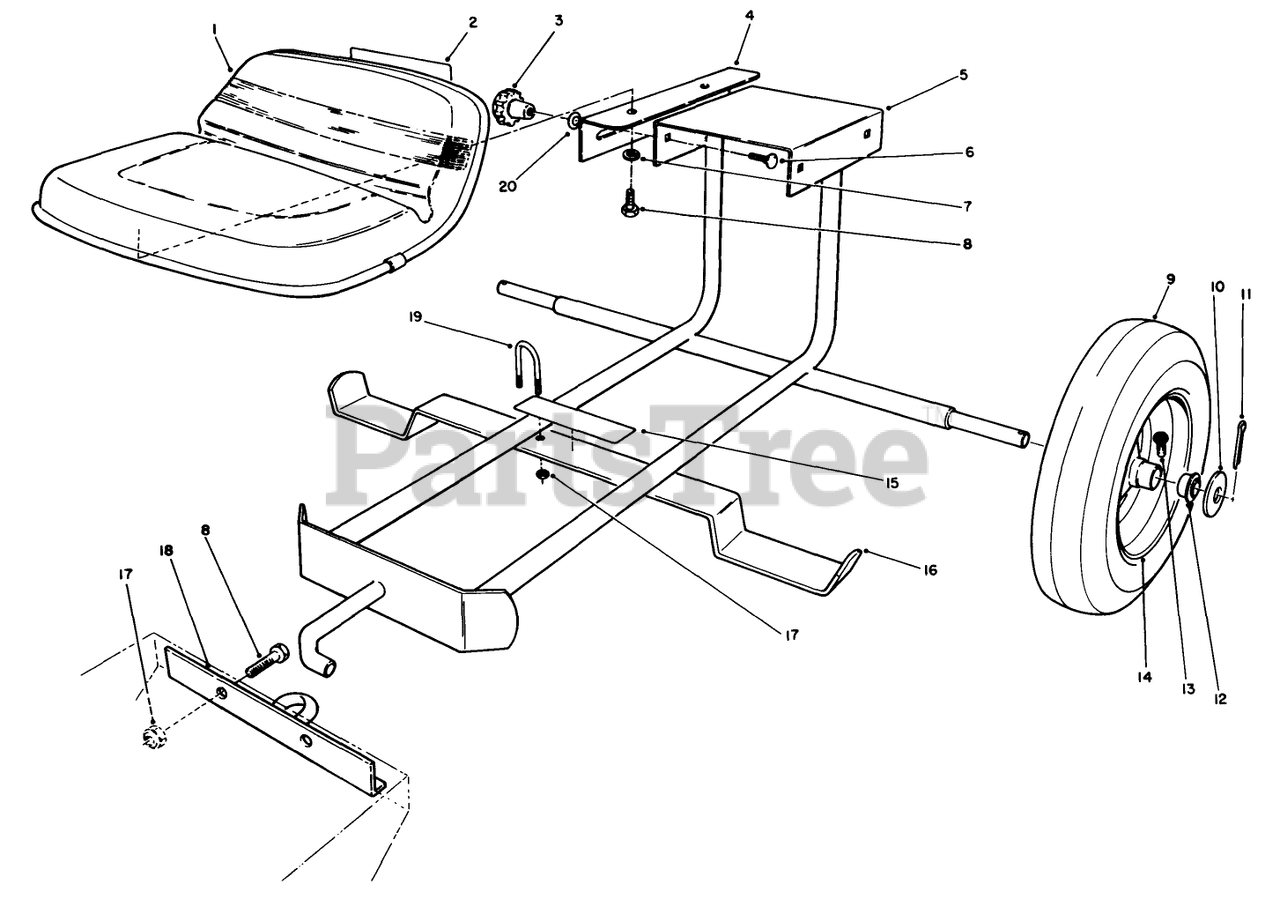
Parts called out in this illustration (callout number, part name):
2	DECAL
6	BOLT-CARR
7	WASHER-LOCK
8	SCREW-HH
10	WASHER-FLAT
11	PIN-COTTER
13	INNER TUBE VALVE STEM
17	NUT-LOCK, NI
18	HITCH WA *R
19	U-BOLT
20	WASHER-BELLEVILLE
